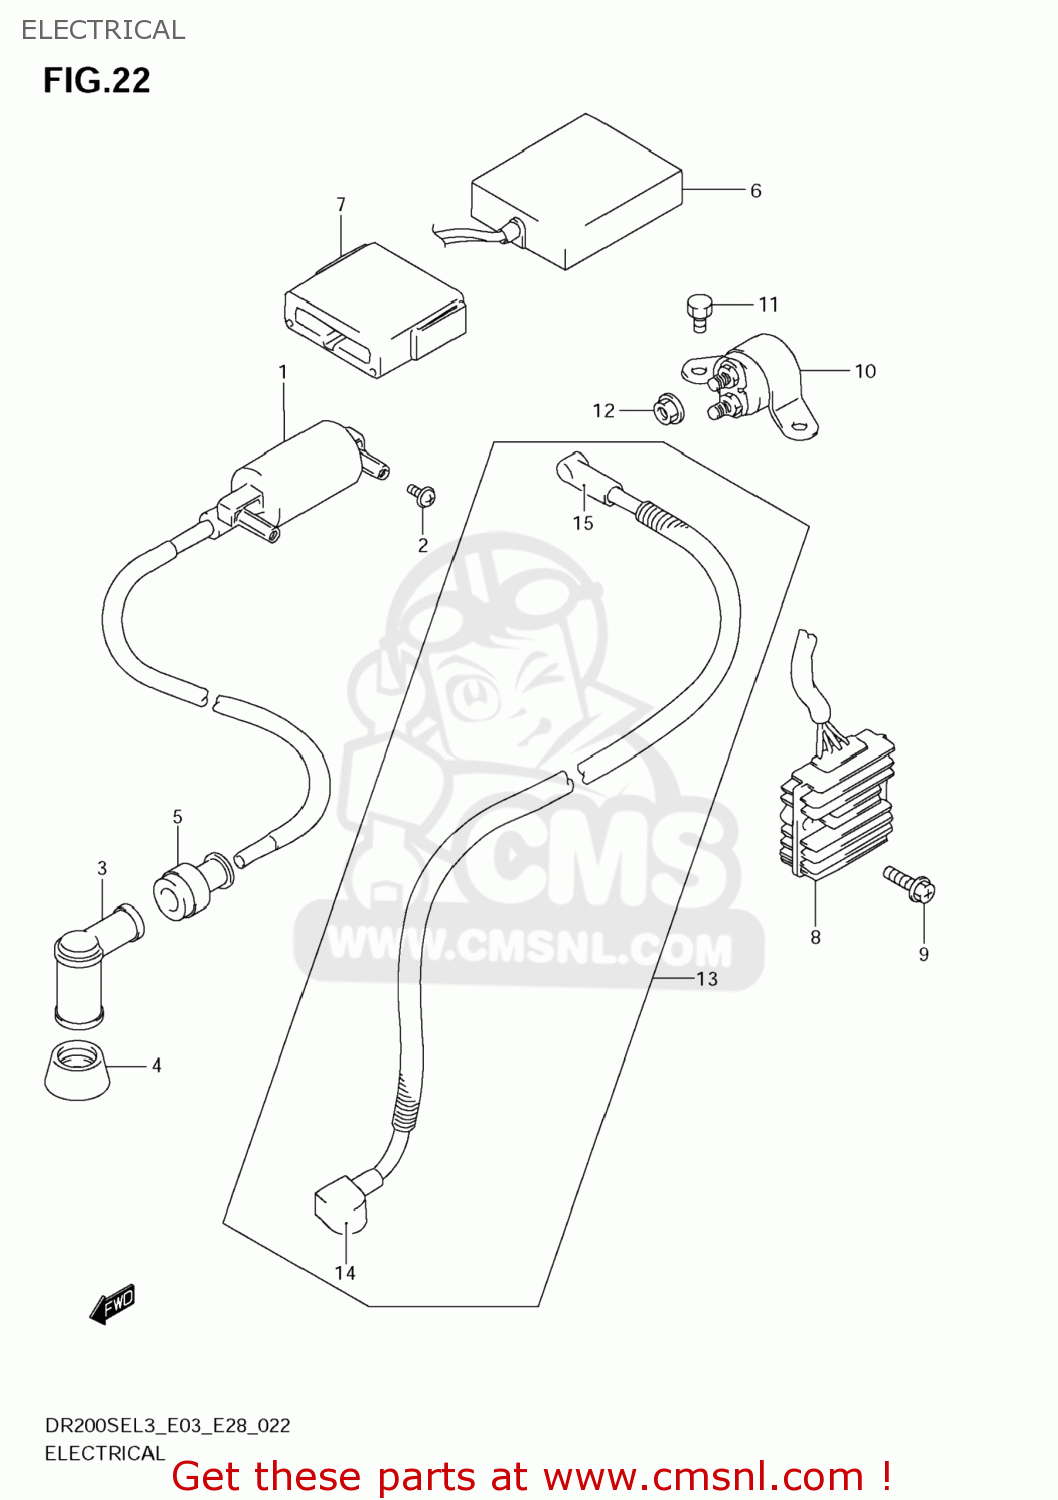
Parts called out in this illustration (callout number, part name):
1	COIL ASSY,IGNITION
2	SCREW
3	CAP ASSY,SPARK PLUG
4	SEAL,SPARK PLUG
5	SEAL,HIGH TENSION CORD
6	IGNITOR
7	CUSHION,CDI UNIT
8	RECTIFIER ASSY
9	SCREW
10	RELAY ASSY,STARTING MOTOR
11	SCREW(6X10)
12	NUT
13	WIRE,STARTER MOTOR LEAD
14	CAP,STARTER MOTOR TERMINAL
15	CAP,STARTER RELAY
